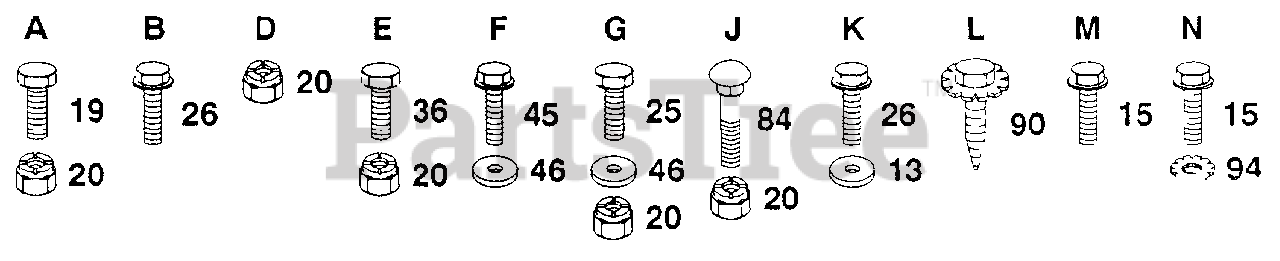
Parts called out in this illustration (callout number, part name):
13	WASHER
15	SCREW
19	BOLT
25	BOLT
26	SCREW
45	SCREW
46	WASHER
84	BOLT
94	LOCKWASHER
